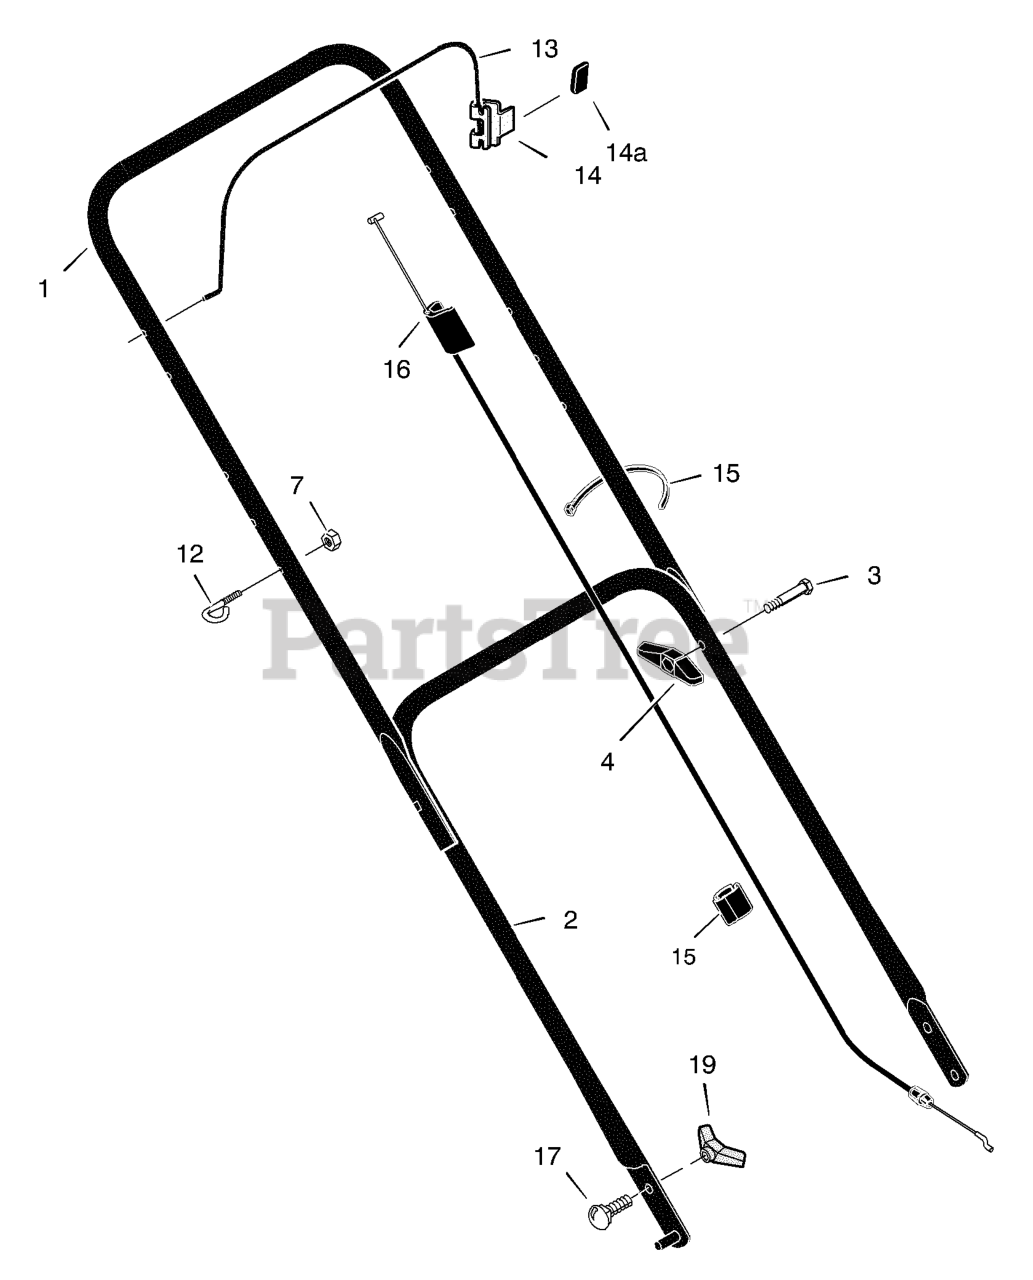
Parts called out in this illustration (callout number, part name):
1	Handle, Upper (Black)
2	Handle, Lower (Black)
4	Knob, Plastic
7	Locknut
12	Guide, Rope
13	Engine Stop Lever
14	Bracket, Stop Lever
14A	Sleeve, Vinyl
15	Fastener, Cable
16	Engine Stop Cable
17	Bolt, Carriage
19	Knob, Plastic
